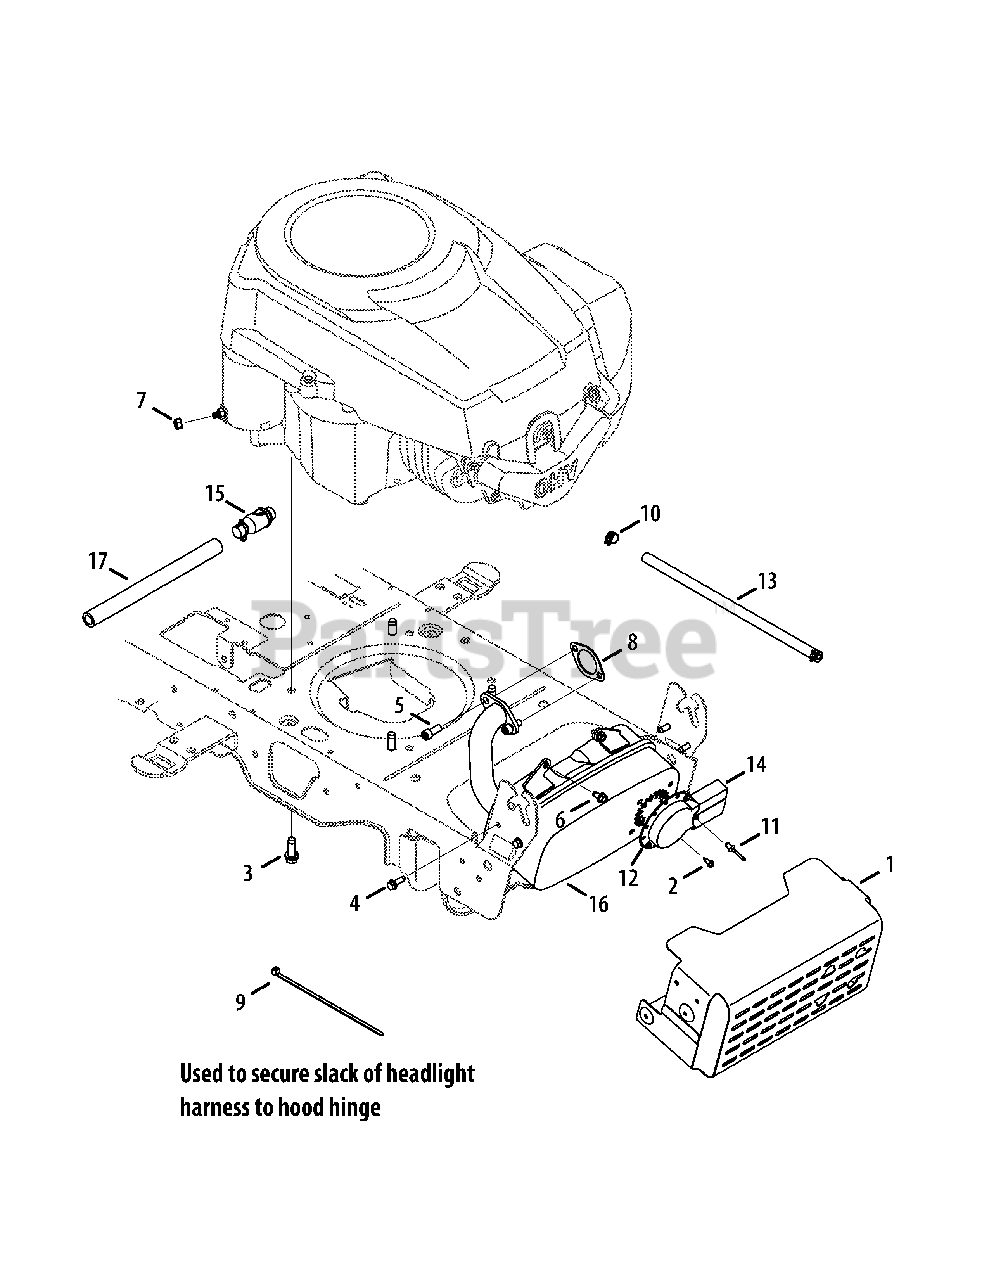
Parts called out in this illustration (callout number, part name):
1	Shield Ass’y, Muffler
2	Screw, Ab, #8-18, 0.500,
3	Screw, Self-tapping, 3/8-16, 1.000,
4	Screw, Self-tapping, 1/4-20, 0.500,
5	Screw, Socket Head, 5/16-18, .750
6	Screw, Self-tapping, 1/4-20x.625,
7	Nut, Sems, 1/4-20
8	Gasket, Exhaust
9	Cable, Tie, 3/16 x .05 x 7.4
10	Clamp, Hose, .490 Dia.
11	Rivet, Pop, .188 Dia x .300
12	Deflector, Muffler
13	Hose, Fuel, Low Permeation, 1/4
14	Deflector, Muffler, Long
16	Muffler, Single, Kohler
17	Hose, Extension, Oil Drain
